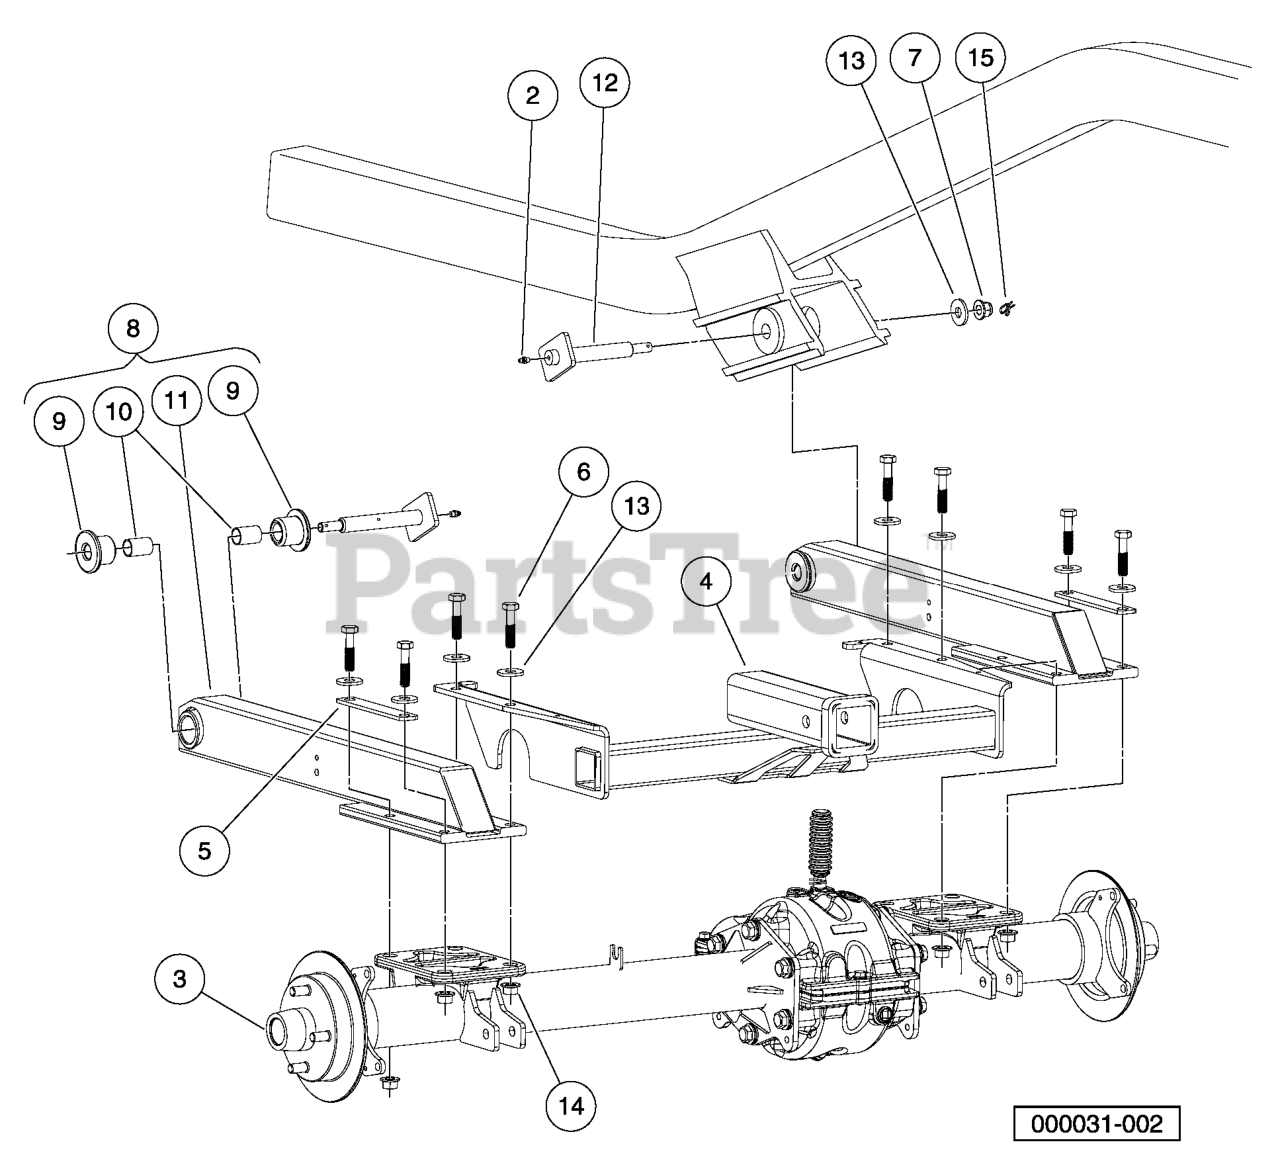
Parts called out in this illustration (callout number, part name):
1	Instl, Rear Suspension
2	FITTING, 1/4-28 THRD FRM GREAS
3	CENTER CAP, RUBBER
4	WELDMENT, RECEIVER, REAR
5	WASHER, STRIP, SWINGARM
6	BOLT FLG, M12X1.75X50
7	NUT FLG, M12X1.75, NYLON GR 10
8	Sub Asm Swingarm
9	BUSHING, PIVOT, URETHANE
10	BUSHING, TEFLON
11	SWINGARM, REAR, AWD
12	PIN, SWINGARM, WELDMENT
13	WASHER, M12 HARD REGULAR
15	COTTER-RUE RING
